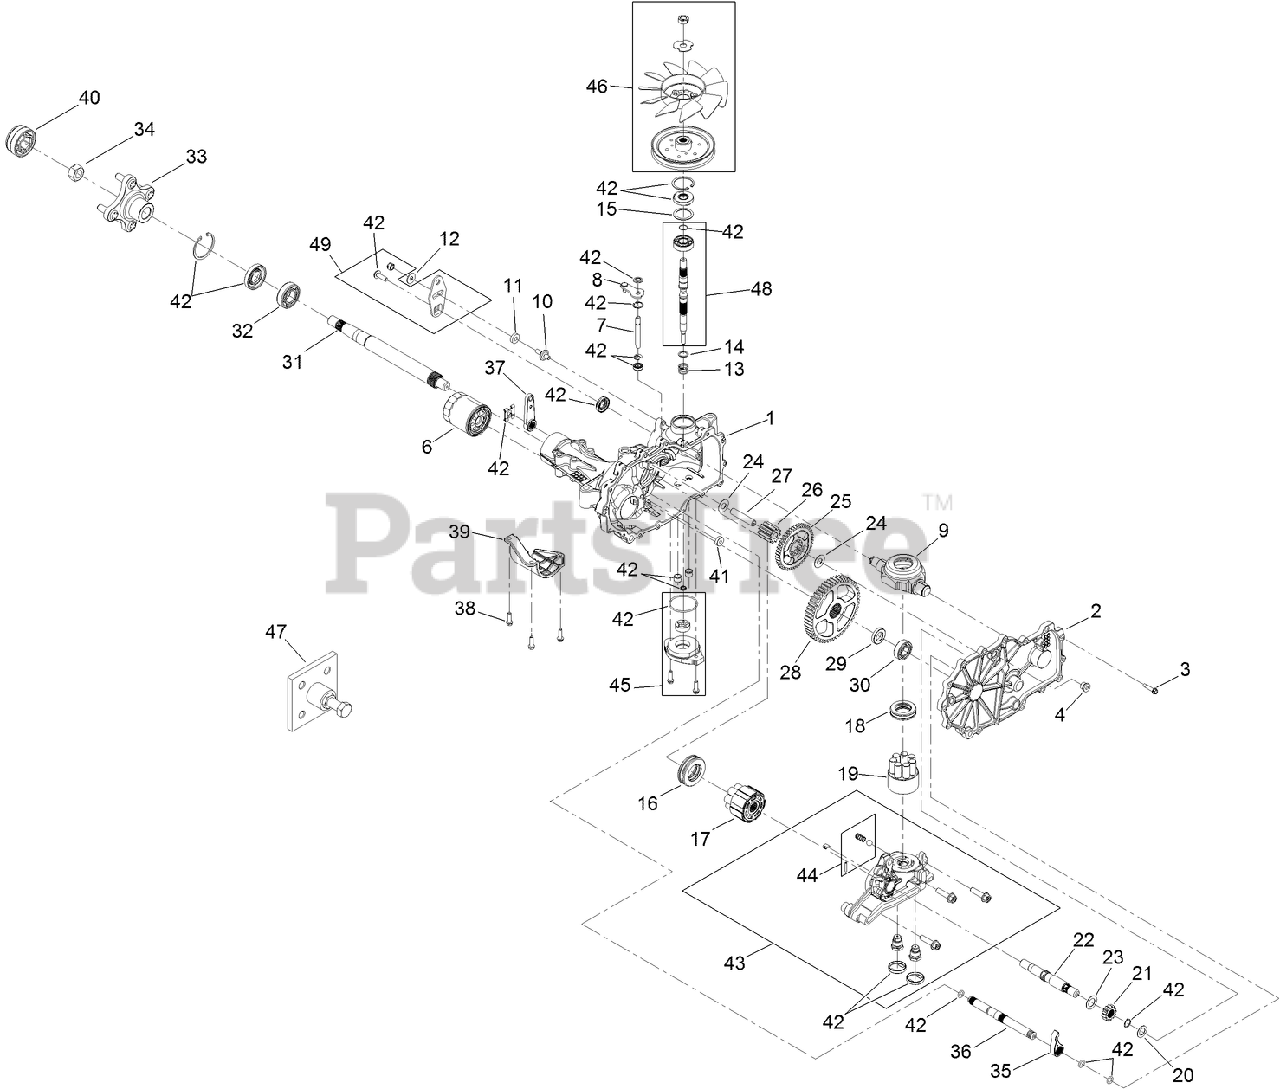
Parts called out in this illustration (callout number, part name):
1	LH MAIN HOUSING KIT
2	LH SIDE COVER KIT
3	SCREW-HHF
4	PLUG-THREAD, STRAIGHT
6	ELEMENT-OIL FILTER, HYD
7	ROD-BYPASS
8	ARM-BYPASS
9	SWASHPLATE-TRUNNION
11	PUCK-FRICTION
12	WASHER
13	SPRING-COMPRESSION
14	WASHER
15	SPACER
16	Bearing-Thrust
17	MOTOR CYLINDER BLOCK KIT
18	BEARING-THRUST, PLASTIC CAGE
19	7 PISTON BLOCK ASM
20	WASHER-FLAT
21	GEAR-13T
22	SHAFT-MOTOR
23	WASHER
24	WASHER
25	GEAR-46T
26	GEAR-11T
27	PIN-JACKSHAFT
28	GEAR-54T
29	SPACER
30	BEARING-BALL
31	SHAFT-AXLE
32	BEARING-BALL
33	HUB KIT
34	NUT-HUB
35	PAWL-BRAKE
36	SHAFT-BRAKE, INBOARD
37	HANDLE-BRAKE
38	SCREW-HF
39	GUARD-FILTER, LH
40	COVER-NUT, AXLE
41	MAGNET-RING
42	SEAL KIT
43	LH CENTER SECTION KIT
44	CHARGE RELIEF KIT
45	CHARGE PUMP KIT
46	FAN AND PULLEY KIT
47	PULLER-HUB, 4 BOLT
48	INPUT SHAFT KIT
49	CONTROL ARM KIT
